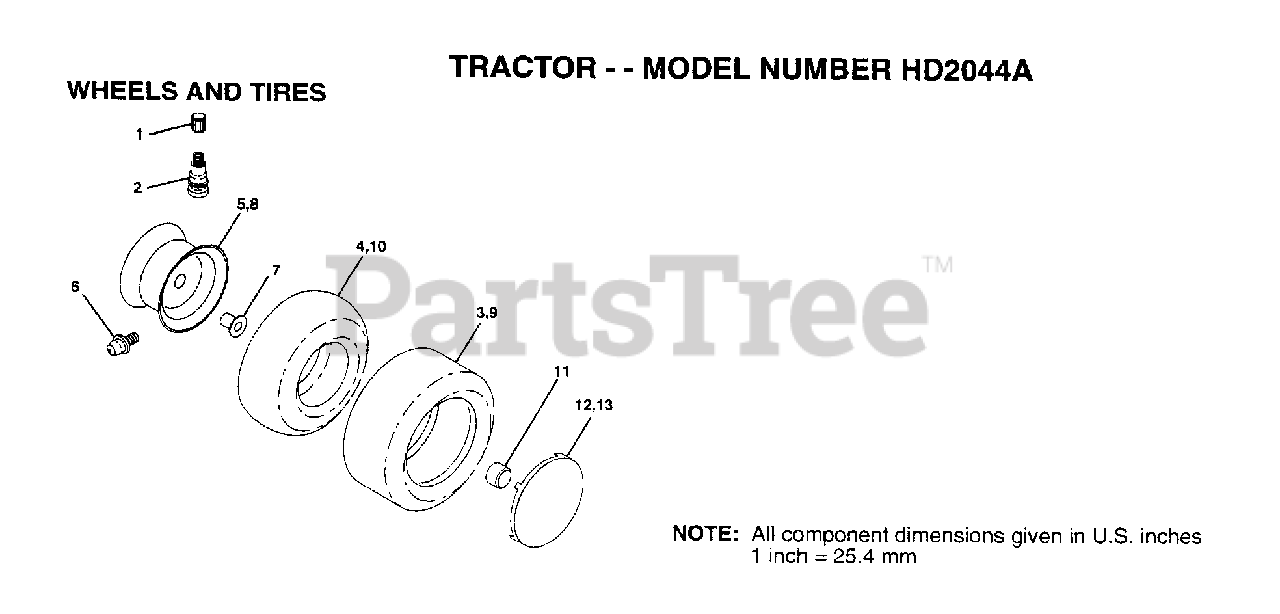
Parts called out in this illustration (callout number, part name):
1	VALVE CAP
2	VALVE STEM LT
4	TUBE.5.3/4.5/6
5	"RIM ASM 8"" FRT"
6	FITTING LT
7	"FLANGE, BEARING"
8	RIM.REAR.
10	TUBE.23X8/10-12
11	HUB CAP
